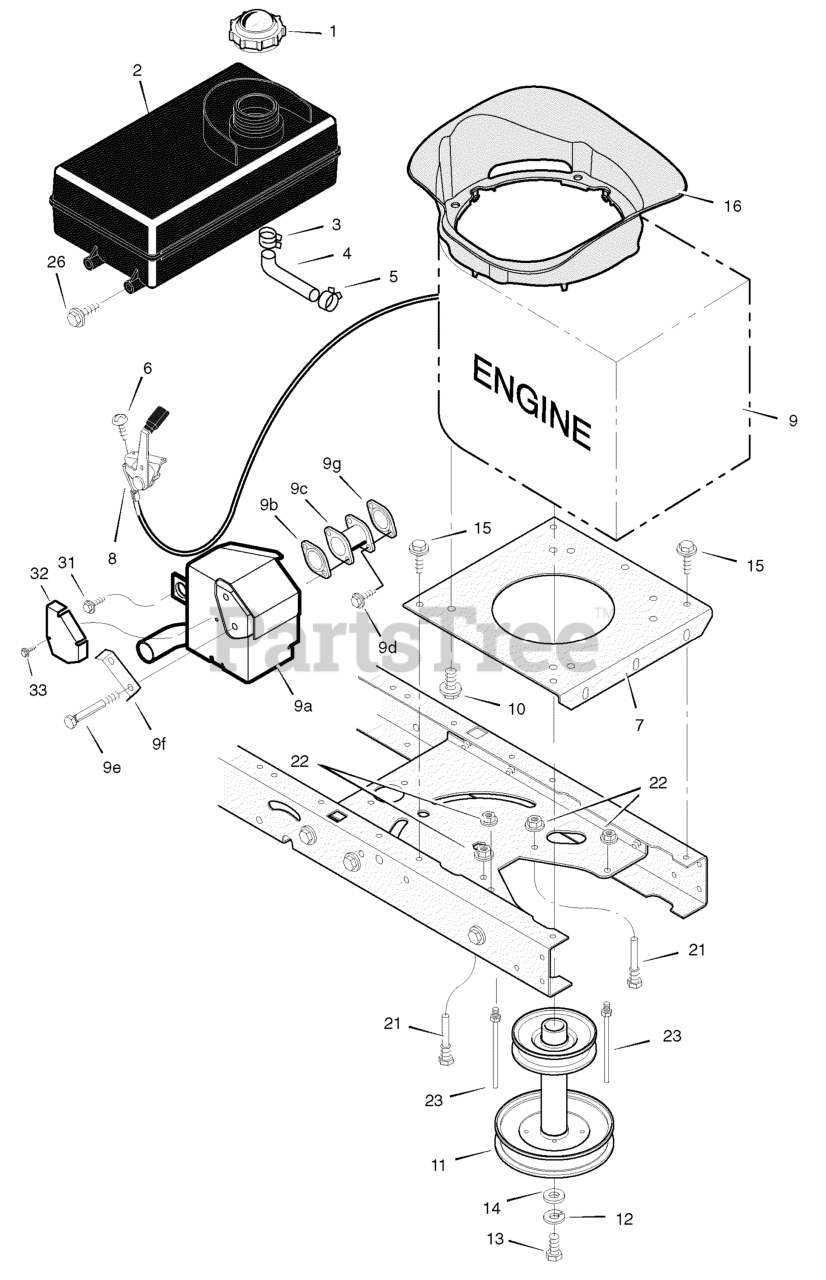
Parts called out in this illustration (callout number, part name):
1	Fuel Cap
2	TANK, Fuel 1.4 Gal.
3	Hose Clamp
4	Fuel Line (Must cut to length)
5	Hose Clamp
6	Screw
7	Plate, Engine
8	Throttle Control
9	Engine, BRIGGS & STRATTON *
10	Bolt, Engine Mount
11	STACK PULLEY ASSEMBLY
12	Lockwasher
13	Bolt, Hex
14	Washer
15	Screw
21	Guide, Belt
22	Nut, Flange
23	Guide, Belt
31	Screw
32	Shield, Heat
